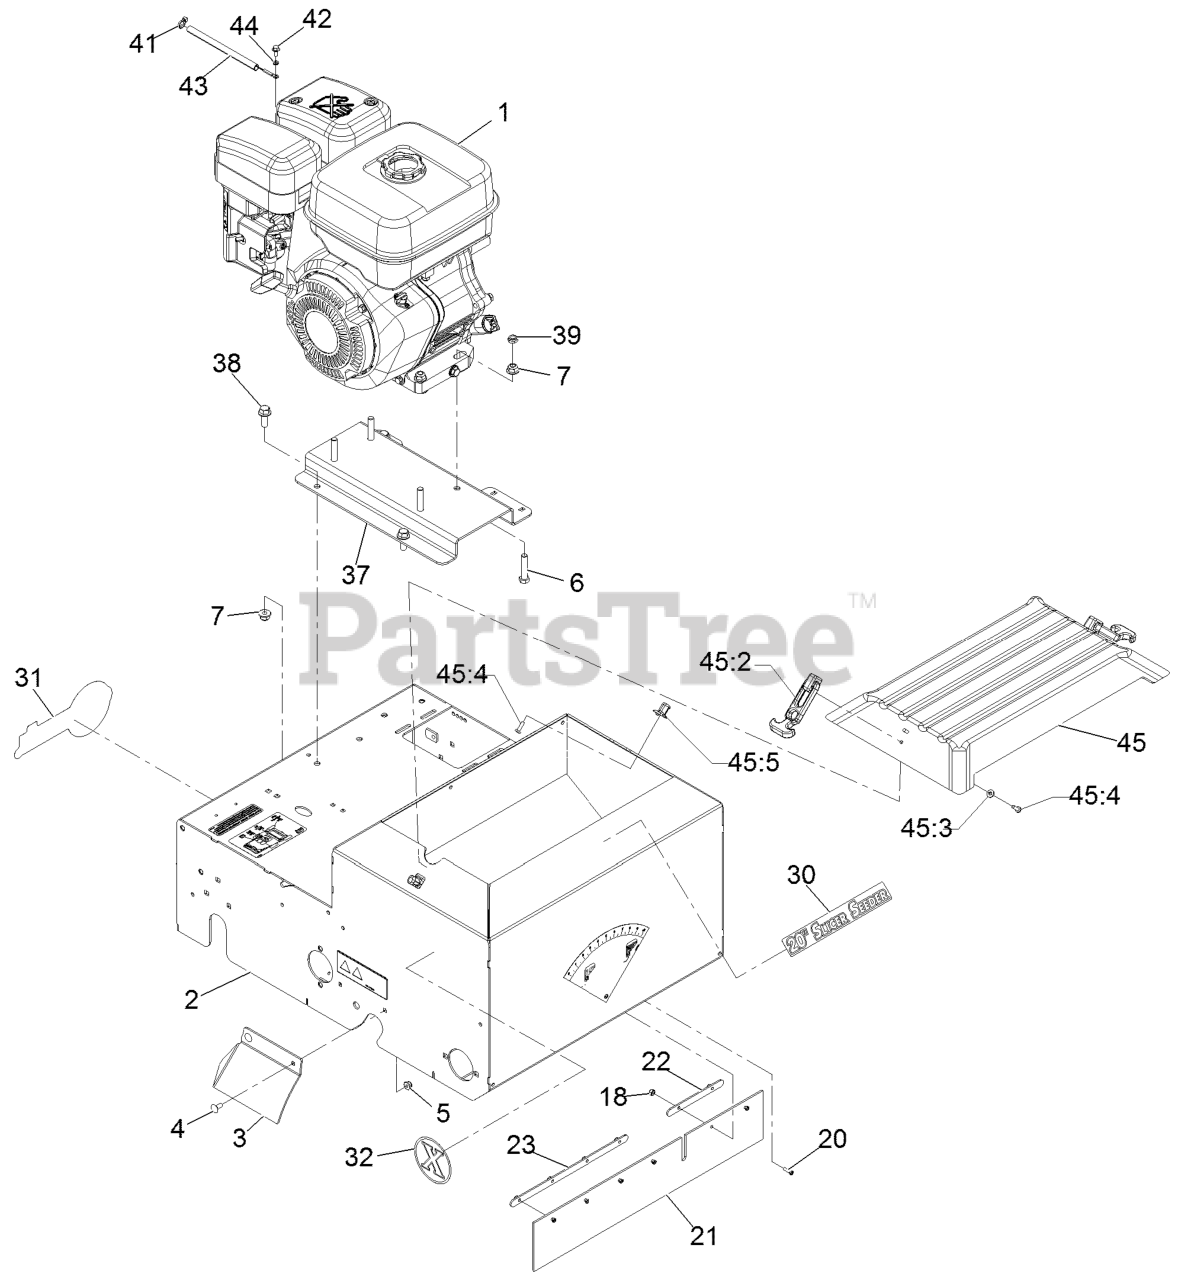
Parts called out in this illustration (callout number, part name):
2	FRAME ASM
4	SCREW-CARR
6	SCREW-HH
7	NUT-HF, NI
18	NUT-LOCK
20	SCREW-SHH
21	GUARD-DUST
22	PLATE-RETAINER
23	PLATE-RETAINER
30	DECAL-SLICER SEEDER 20
31	DECAL,EXMARK LOGO
32	DECAL-EXMARK X-LOGO 3.26
37	PLATE-ENGINE
38	SCREW-HHF 3/8-16 X 1
41	TIE-CABLE
42	SCREW-HFH
43	RFI-SHEATHING
44	WASHER-LOCK, SPRING
45	SEEDER COVER KIT
45:2	LATCH-RUBBER
45:3	WASHER-FLAT
45:4	SCREW-PPH
45:5	LATCH-KEEPER
